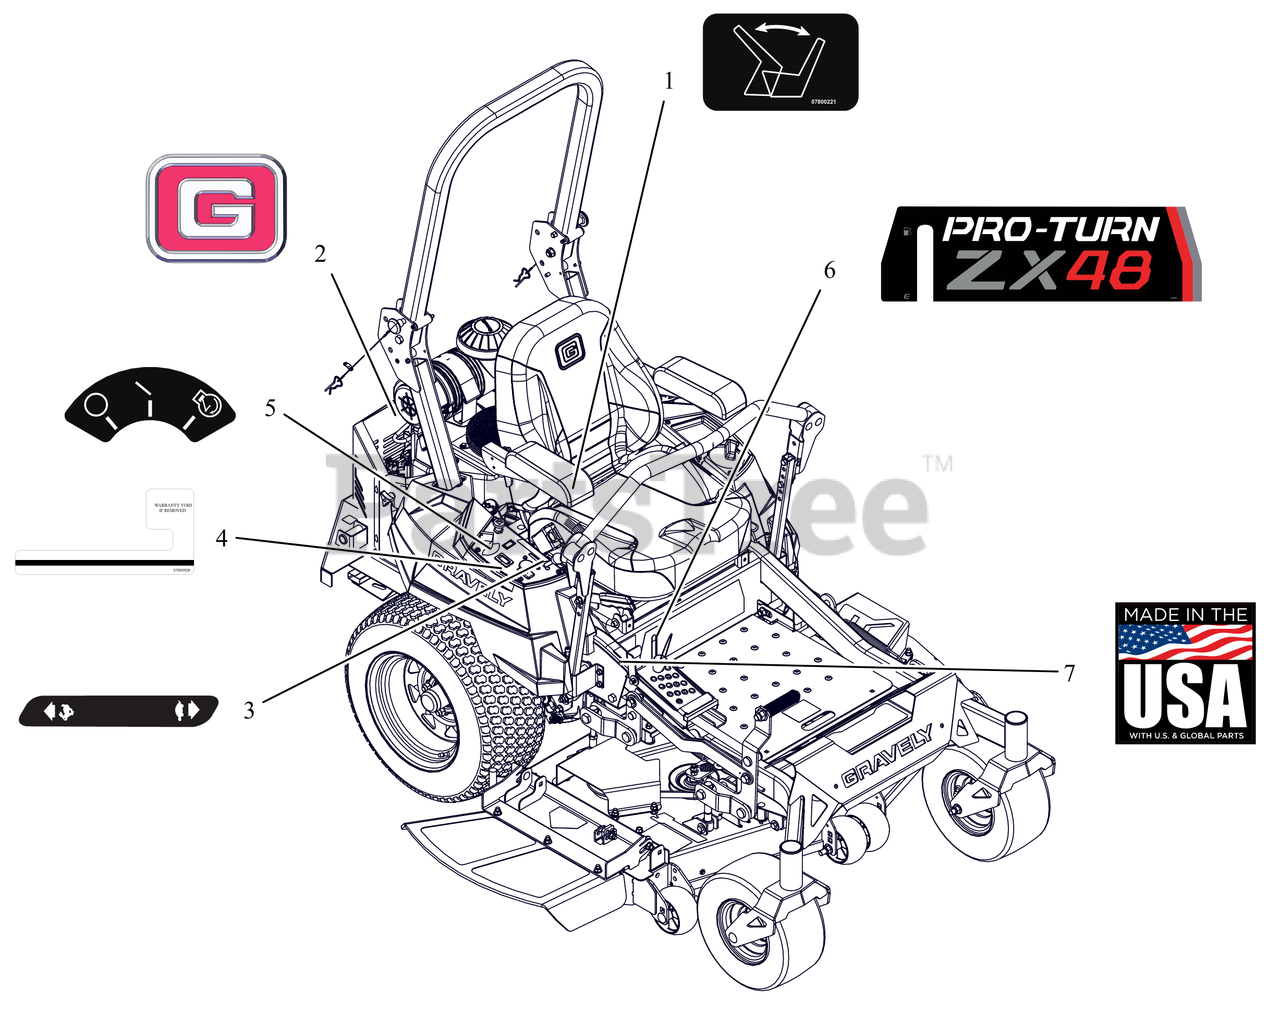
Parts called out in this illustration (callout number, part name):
1	DECAL - SEAT RELEASE
2	DECAL, GRAVELY BRAND
3	DECAL, DASH DECAL
4	DECAL,HOURMETER - SECURITY
5	DECAL, KEYSWITCH
6	DECAL, PROTURN ZX 48
7	DECAL, MADE IN USA
